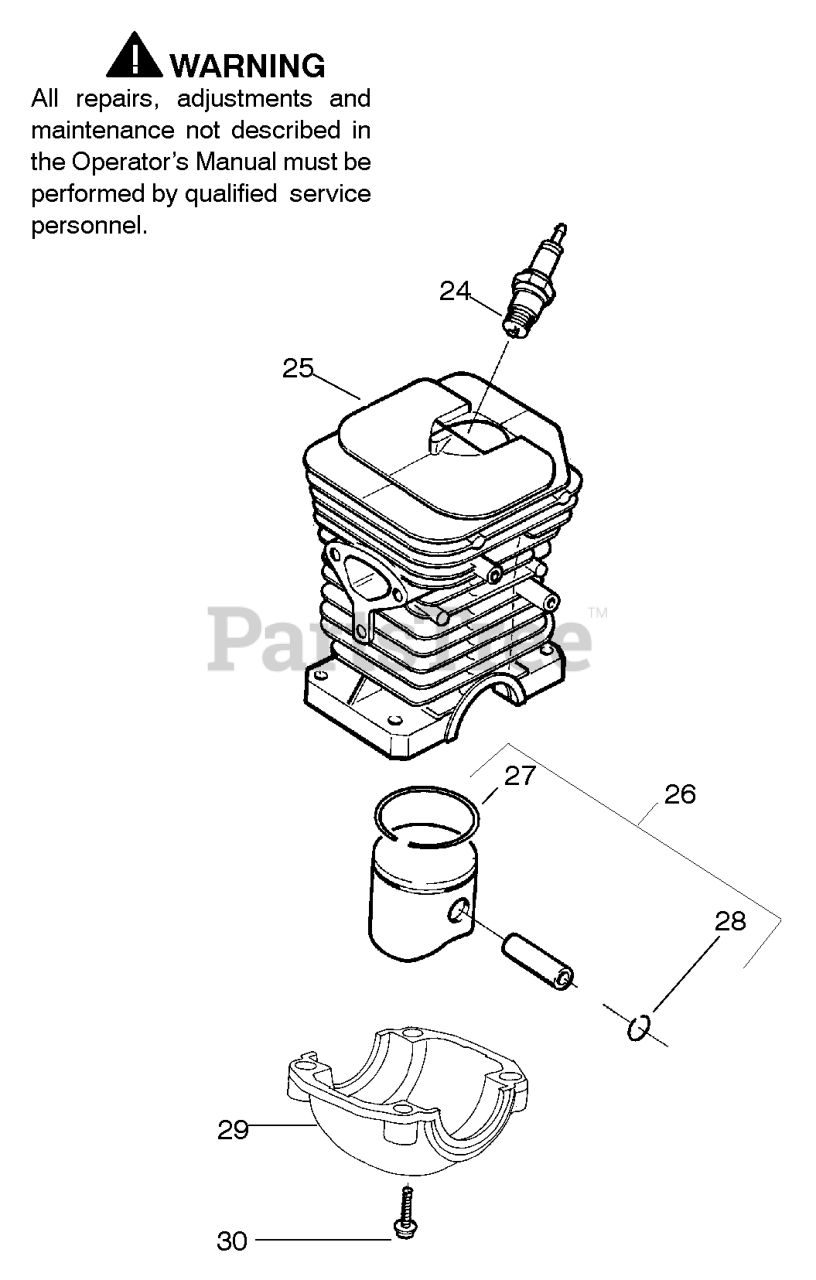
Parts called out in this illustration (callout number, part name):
24	Spark Plug (RCJ-7Y)
25	CYLINDER ASSY/136
26	PISTON KIT/136
27	PISTON RING 36
28	C-CLIP,PSTN PIN 36/41
29	CAP-CRANKSHAFT
30	SCREW-M5-0.8 X 25MM(TAP)
